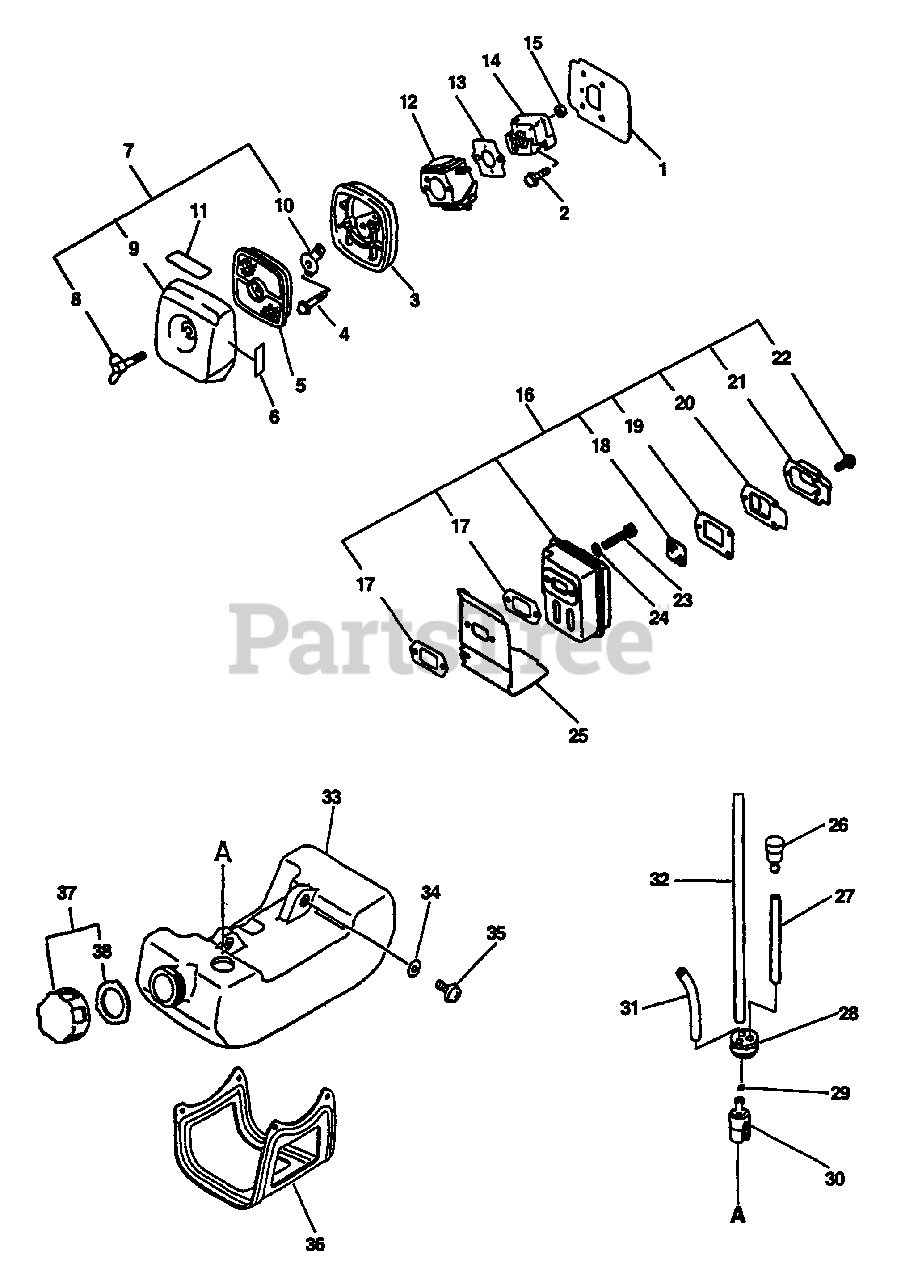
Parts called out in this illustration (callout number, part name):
1	SHIELD, INTAKE
2	SCREW - 5X20
3	AIR FILTER CASE ASSY
4	SCREW - 5X65
5	FILTER, AIR - SINGLE LAYER
6	LABEL - CHOKE
7	COVER, AIR FILTER - GRAY
8	THUMBSCREW
9	COVER, AIR FILTER - GRAY
10	PLATE, PREVENT
11	LABEL - CHOKE
12	CARBURETOR WT-424A
13	GASKET, INTAKE
14	INSULATOR, INTAKE
16	MUFFLER ASSY
17	GASKET, EXHAUST
18	SCREEN, SPARK ARRESTOR
19	GASKET, EXHAUST
20	GASKET, EXHAUST - INNER
21	GUIDE, EXHAUST - OUTER
22	SCREW - 4X10
23	SCREW - 5X55
24	WASHER - 5
25	COVER, EXHAUST
26	VENT, FUEL TANK
27	PIPE - 3X5X70 -- BLACK
28	GROMMET
29	CLIP - 6
30	FILTER, FUEL
31	PIPE - 3X6X80 -- CLEAR
32	PIPE - 3X5X180 -- BLACK
33	TANK, FUEL
34	WASHER - 5
35	SCREW - 5X16
36	GUARD, FUEL TANK
37	CAP ASSY
38	GASKET, CAP
